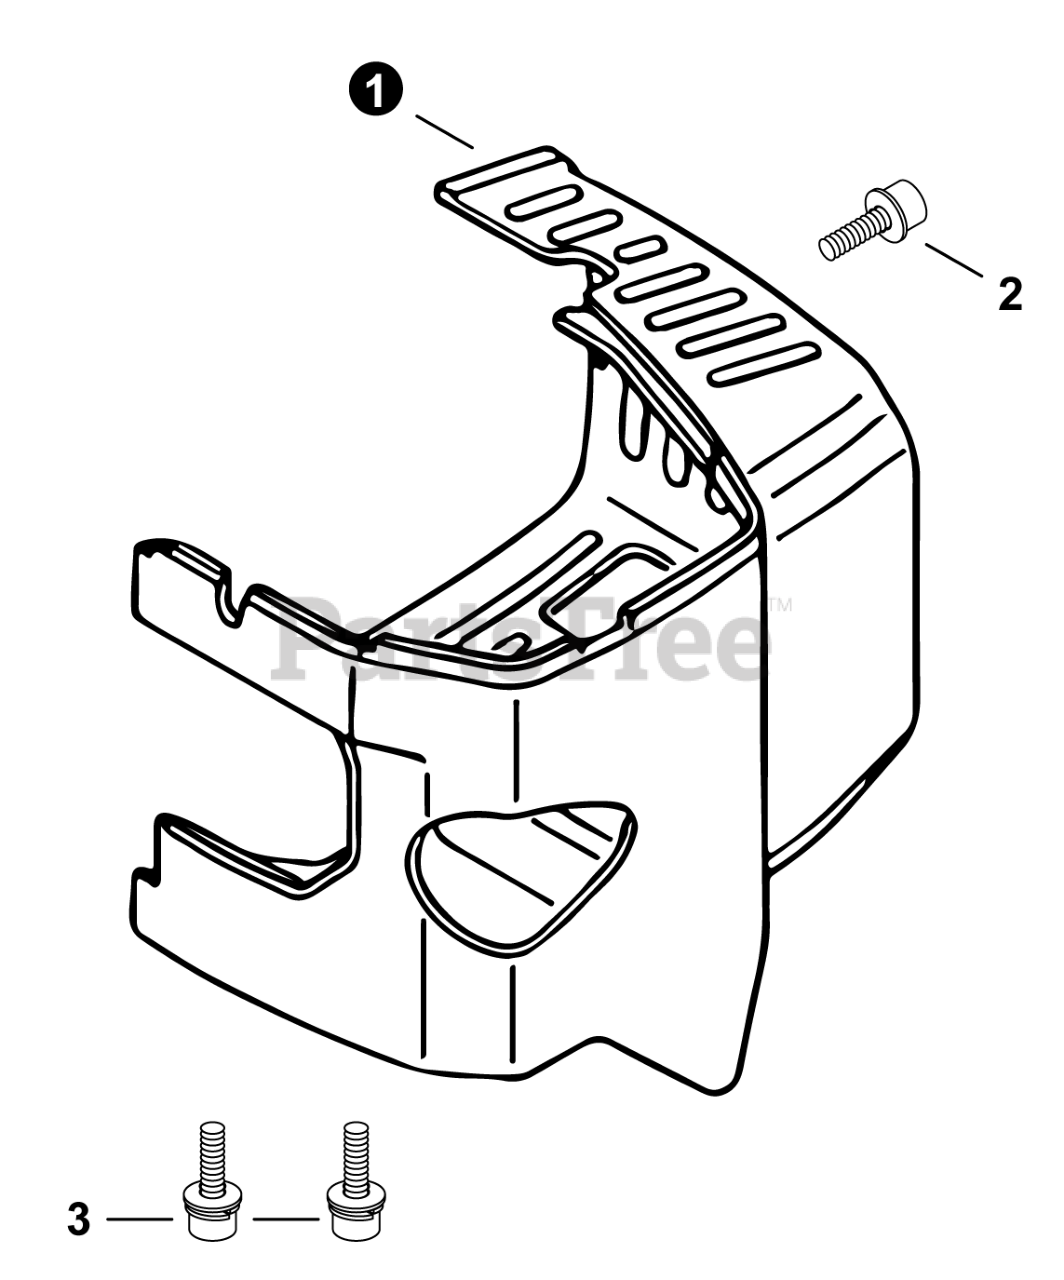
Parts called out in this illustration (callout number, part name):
1	COVER, ENGINE
2	BOLT 4x8
3	SCREW 4x18
